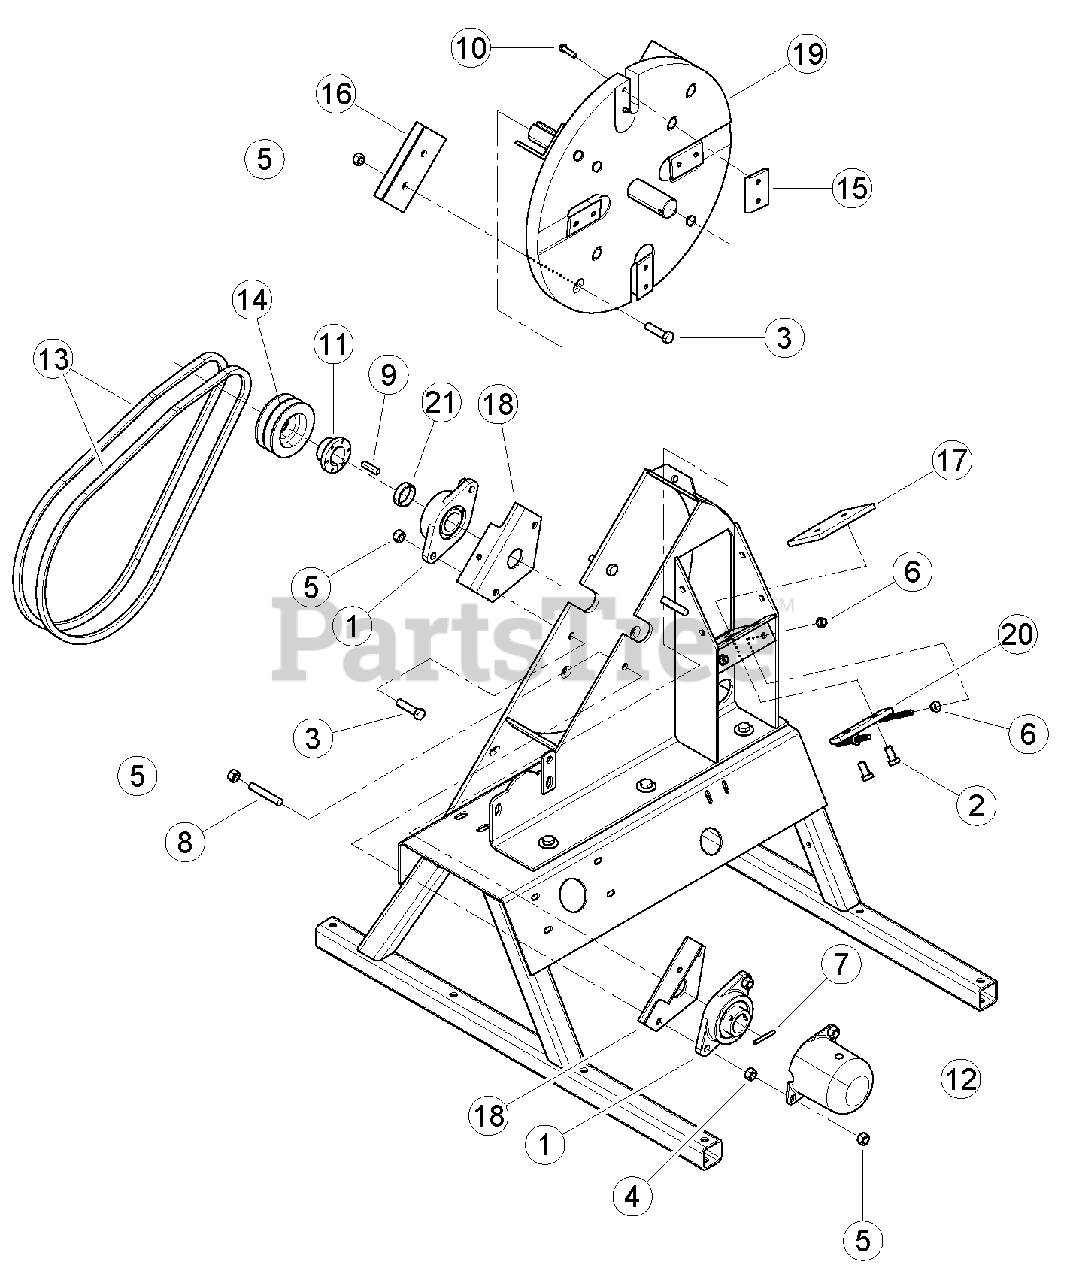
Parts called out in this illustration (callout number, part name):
1	BEARING, 1-1/2" 2-BOLT SET SCREW
2	BOLT, 1/2 X 1 HEX HD GR5 ZP
3	BOLT, 1/2 X 2 HEX HD GR5 ZP
4	NUT, 1/2 HEX NC ZP
5	NUT, 1/2 CENTERLOCK GRB ZP
6	NUT, 3/8 SERRATED FLANGE NC ZP
7	SPRING PIN, 1/4 X 2 LONG
8	STUD, 1/2-13 X 3 LONG B7 ZP
9	KEY, 5/16 SQUARE X 1-1/2 LONG (WAS 15498, REMOVED)
10	BOLT, 5/16 X 1-1/4 HHD GR8 PATCH
11	BUSHING, SH 1-1/2"
12	CAP, LARGE SHAFT
15	KIT, CHIPPER BLADE
17	ANVIL, 4 INCH CHIPPER
18	PLATE, BEARING MOUNT
20	WELDMENT, BLOCK ADJUSTOR
